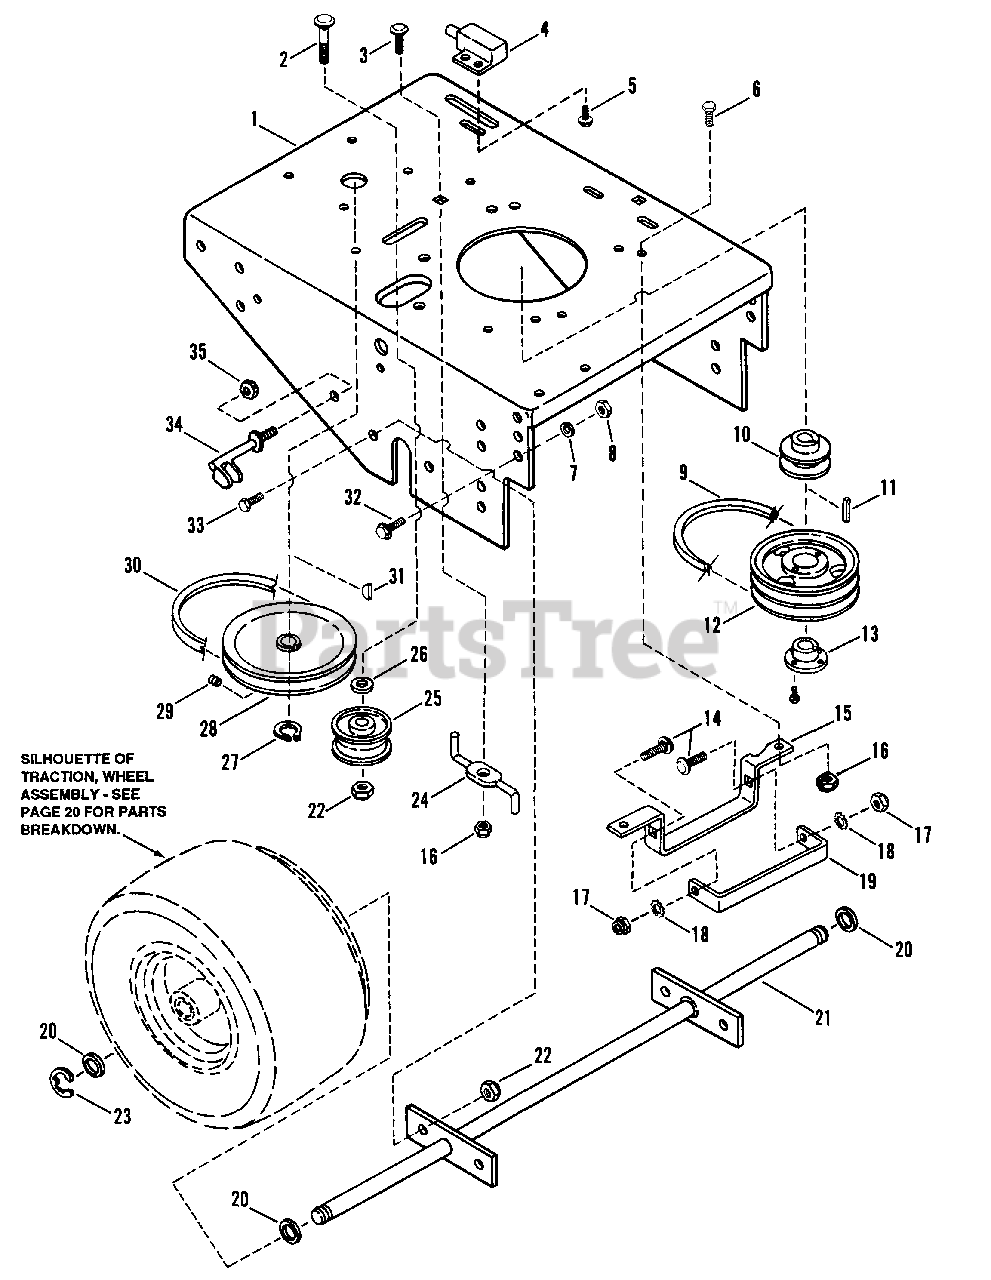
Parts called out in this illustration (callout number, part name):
1	REAR DECK WELDMENT
2	BOLT, 3/8-16 x 1 3/4" Grade 5 Short Neck Carriage
3	BOLT, 5/16-18 x 1" Short Neck Carriage
4	SWITCH, Blade
5	SCREW, #12-14 x 1/2" Slotted Hex Head Flange, Self-Tapping
6	BOLT, 5/16-18 X 3/4 GD5
7	WASHER, 1/2" Split Lock
8	NUT, 1/2-13 HEX
9	BELT, Engine/Deck, 36"
10	PULLEY, Engine/Transmission
11	KEY, 1/4" x 1/4" x 2 1/2" Square
12	PULLEY, Engine/Deck
13	BUSHING, Taperlock
14	BOLT, 1/4-20 x 1" Grade 2 Short Neck Carriage
15	GUIDE, Engine Belt
16	NUT, 5/16-18 HEX NYLON LOCK
17	NUT, 1/4-20
18	WASHER, 1/4 Internal/External Tooth Lock
19	SUPPORT, Belt
20	BUSHING, Axle
21	AXLE WELDMENT
22	NUT, 3/8-16 HEX NYLON LOCK
23	E-RING, 1"
24	KEEPER, Belt
25	PULLEY, Idler
26	WASHER, Flat
27	SNAP-RING, 5/8"
28	PULLEY, Transmission
29	SET SCREW, 1/4-20 X 3/8" CONE
30	BELT, Engine/Transmission
31	KEY, #9 Woodruff
32	BOLT, 1/2-13 x 1 1/4" Hex Head Flange
33	BOLT, 3/8-16 X 1" GD5 CZ
34	SCRAPER, Wheel
35	NUT, 3/8-24 Center Lock
